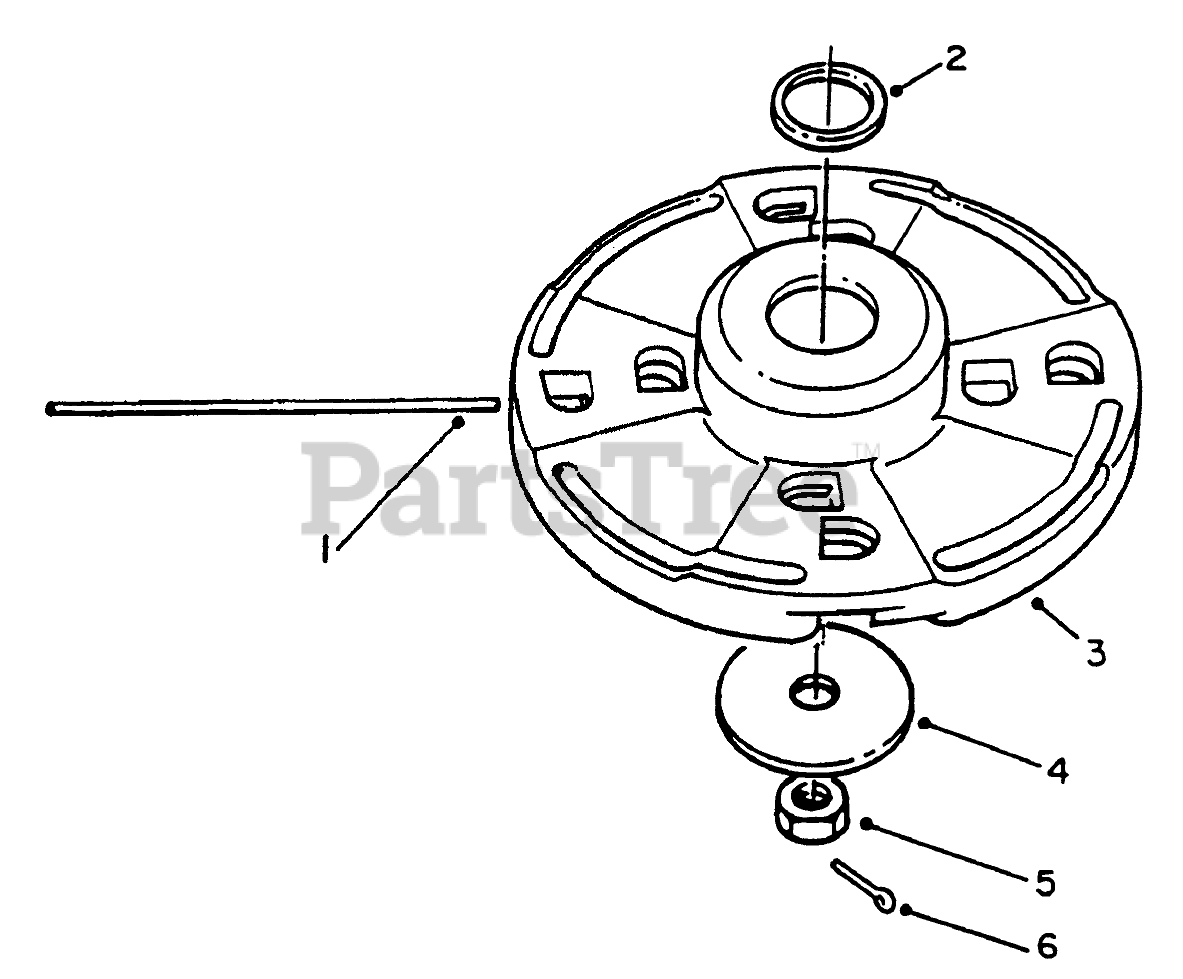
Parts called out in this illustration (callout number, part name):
1	Line-Cutting
2	SPACER
3	Head Assembly (Incl.Ref. #2)
4	WASHER
6	1/16 X 1 LG COTTER PIN
